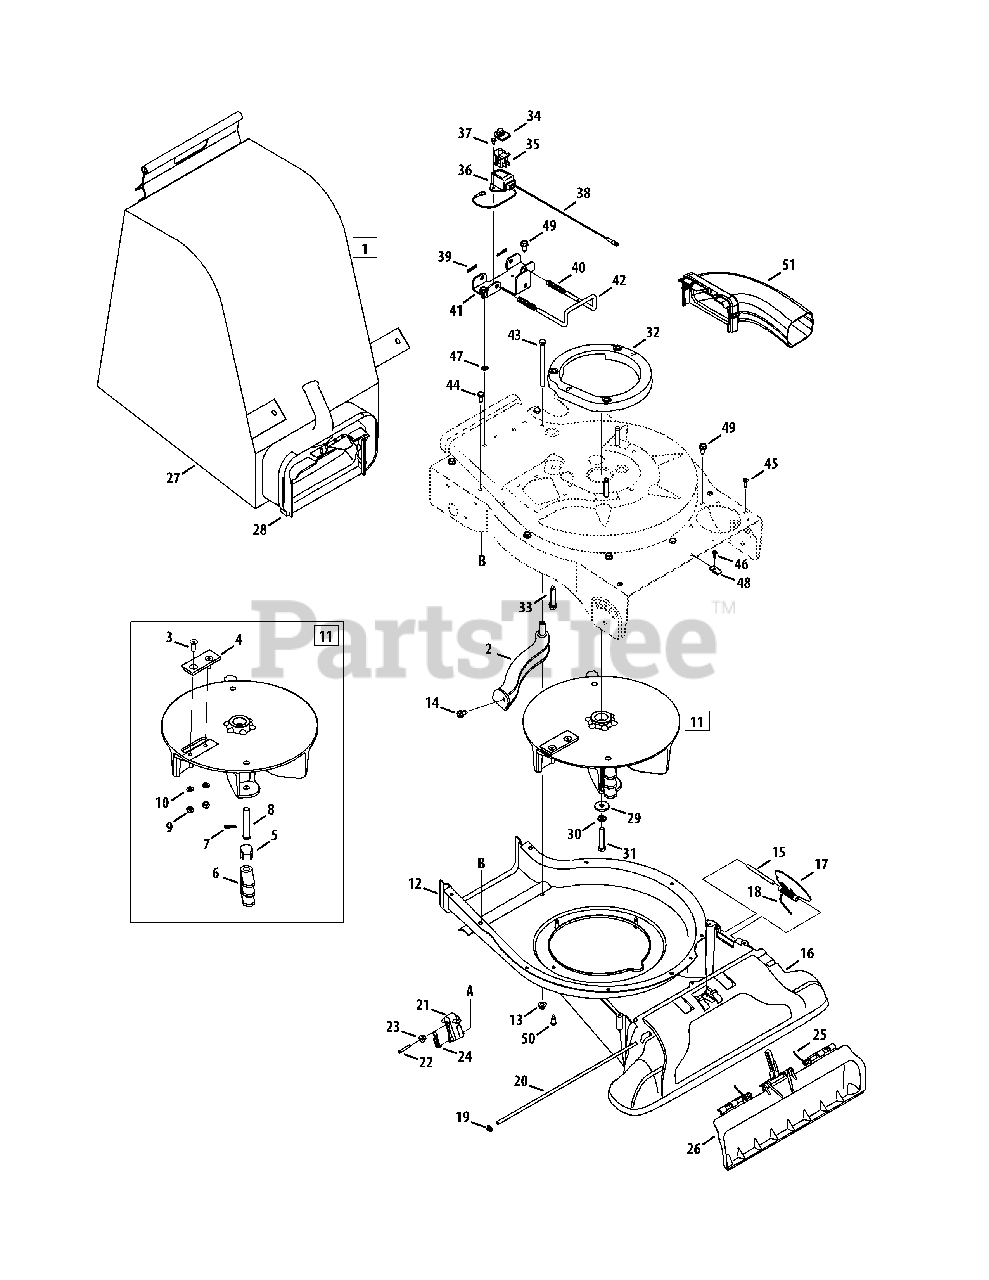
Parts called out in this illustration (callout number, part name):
1	Bag Assembly
2	Screen Assembly
3	Hex Screw 5/16-24 x 1.0
4	Chipper Blade
5	Pin Clip
6	Flail
7	Spiral Pin
8	Clevis Pin
9	Lock Nut, 5/16-24
10	Lock Washer, 5/16
11	Impeller Assembly
12	Lower Flail Housing
13	Flange Lock Nut 5/16-18
14	Screw, 5/16-18 x.500
15	Hinge Pin
16	Nozzle
17	Base Adapter Door
18	Torsion Spring
19	Cap Speed Nut 1/4
20	Pivot Rod
21	Nozzle Door Lever
22	Hex Screw, #8-18 x 1.25
23	Shoulder Spacer
24	Extension Spring
25	Nozzle Door Torsion Spring
26	Nozzle Door
27	Bag
28	Chute Assembly
29	Flat Washer.375 ID x 1.25 OD
30	Lock Washer 3/8
31	Hex Cap Screw, 3/8-24 x 2.75
32	Engine Spacer Assembly
33	Screw, 3/8-16 x 1.875
34	Switch Cover
35	Safety Switch
36	Safety Switch Cover
37	Hex Washer Screw #10-16 x.50
38	Wire Harness
39	Cotter Pin
40	Compression Spring
41	Mounting Bracket
42	Lock Rod
43	Hex Cap Screw 5/16-18 x 4.5
44	Hex Cap Screw 5/16-18 x.625
45	Screw, #12-16 x.750
46	Screw #10 - 16 x.500
47	External L-Washer 5/16
48	Speed Nut
49	Hex Index Screw, 5/16-12 x.750
50	Shoulder Screw, #12-24 x .30 x .46
51	Blower Chute
